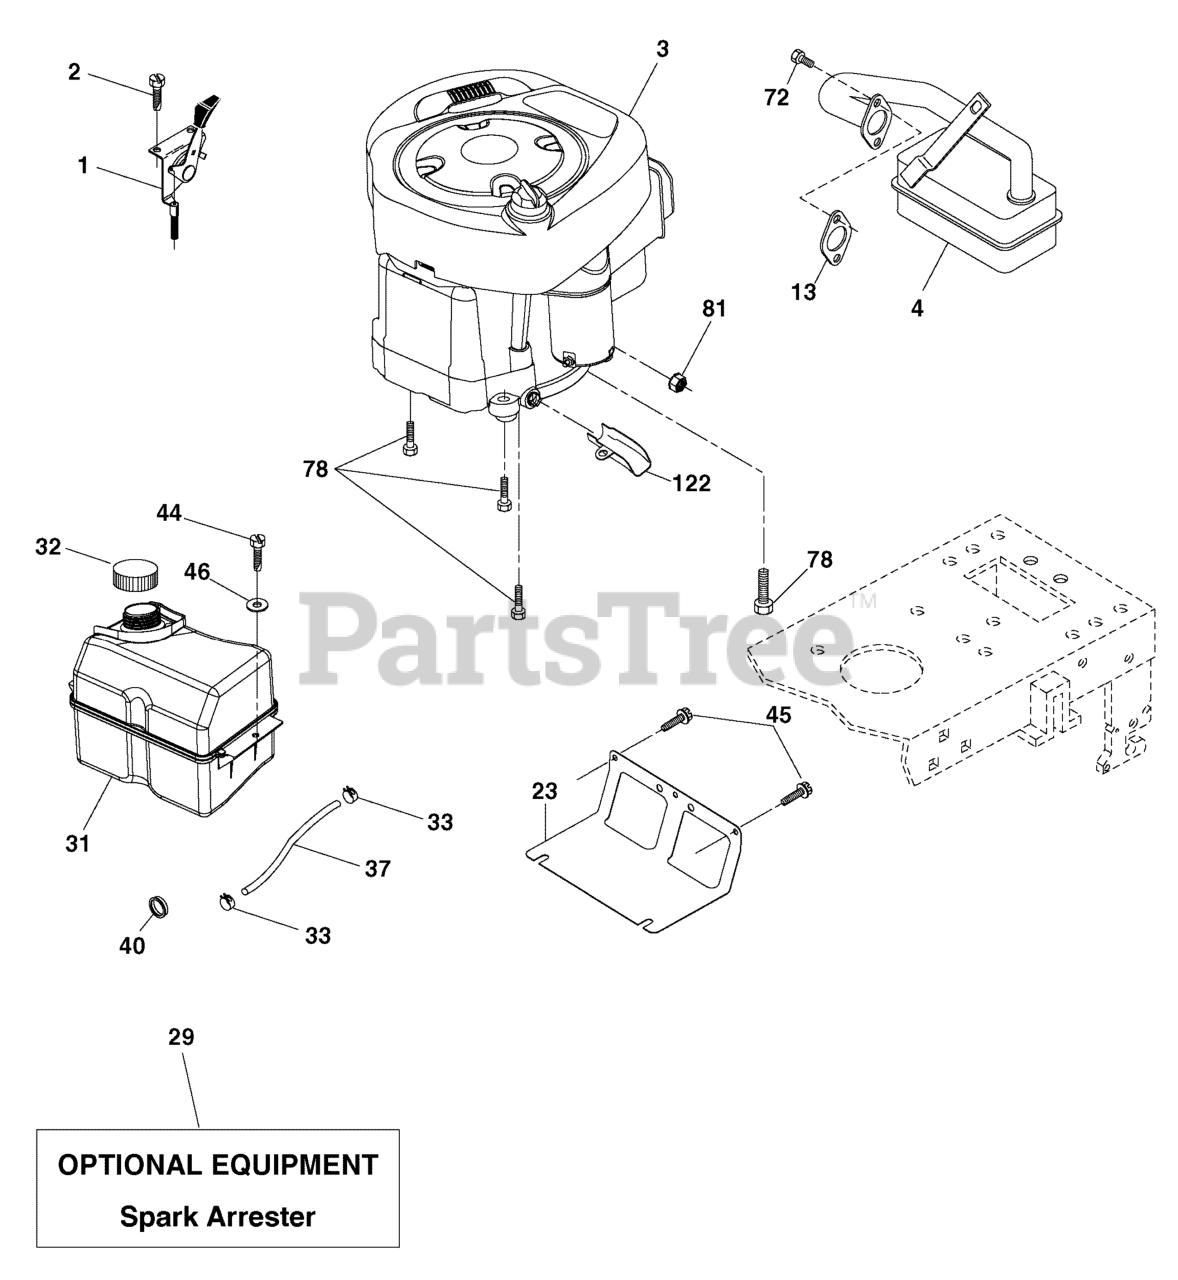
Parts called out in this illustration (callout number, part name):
1	CONTROL Th/Ch
2	SCREW, Hex Thread Cut, 1/4-20 x 1/2
3	ENGINE, B&S Intek
4	MUFFLER, Exhaust B&S
13	GASKET, Eng Tin Plated, 1 313 Id
23	SHIELD, BRN/DBR Guard
29	KIT, Spark Arrestor (Flat Scrn)
31	TANK, Fuel Front
32	CAP, Fuel
33	CLAMP, Hose
37	FUEL LINE, 20"
40	BUSHING, Snap Nylon Black Fuel Line
44	SCREW, Thead Rolling, 1/4-20 x 3/4
45	SCREW, Hex Washer Thead Rolling, 3/8-16
46	WASHER, 9/32 x 7/8 x 16 Ga.
72	SCREW, Socket Head, 5/16-18 x .75
78	SCREW, 3/8-16 x 1-1/4
81	NUT, Keps Hex 1/4-20 UNC
122	EXTENSION, Drain Oil
